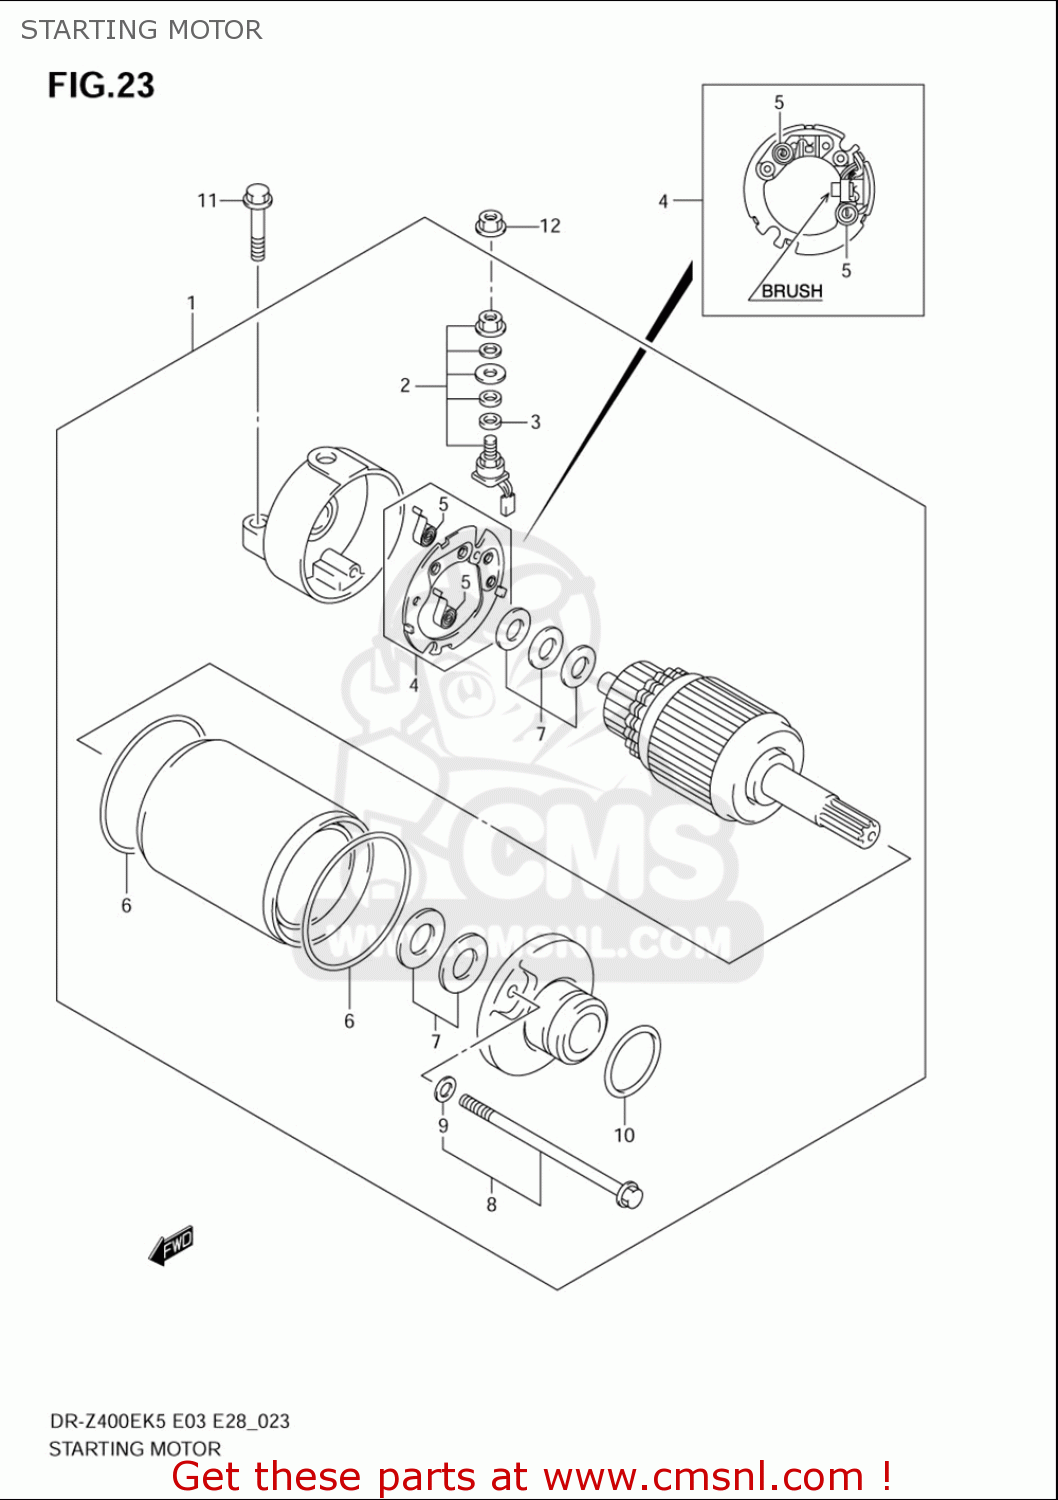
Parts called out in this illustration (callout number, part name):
1	MOTOR ASSY,STARTING
2	BRUSH TERMINAL SET
3	O RING
4	BRUSH HOLDER SET
5	SPRING,BRUSH
6	O RING
7	SHIM SET,STARTING MOTOR
8	BOLT SET
9	O RING
10	O RING(D:3,ID:24.5)
11	SCREW
12	NUT
